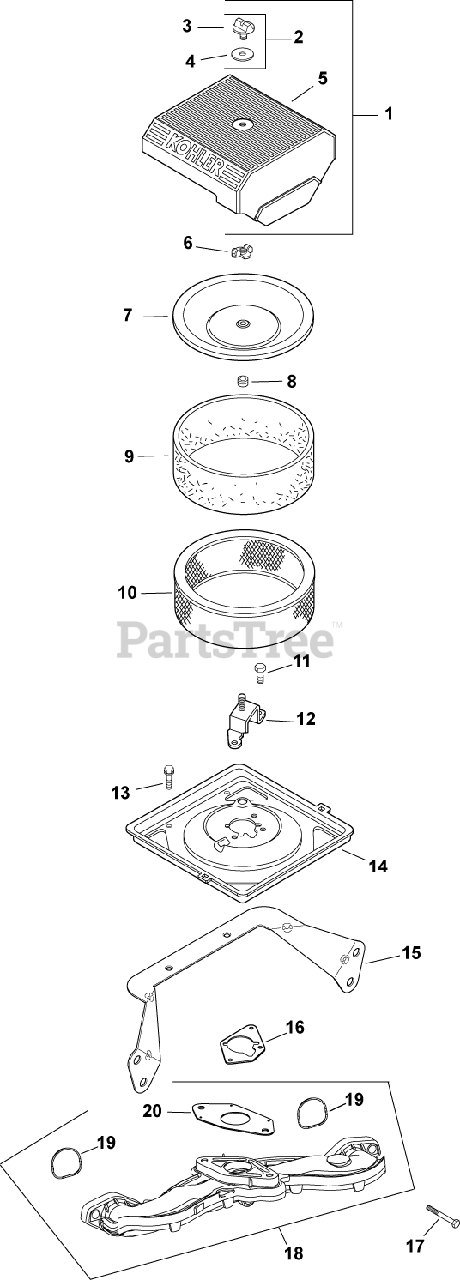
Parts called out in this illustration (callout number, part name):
1	KIT, AIR CLEANER COVER
2	KIT, KNOB W/SEAL
3	KNOB, COVER
5	COVER, AIR CLEANER
6	NUT, WING
7	COVER, INNER AIR CLEANER
8	SEAL, BREATHER
9	PRE-CLEANER (HIGH)
10	ELEMENT, AIR FILTER (HIGH) - Also available Retail Packaged 24 883 03-S1 Air Filter Kit
11	SCREW, FLG THD FRM M6X1.0X16
12	BRACKET, AIR CLEANER-USE 24 126 210-S
13	SCREW, FLG THD FRM M5X.8X10
14	BASE, AIR CLEANER -USE 24 094 88-S
15	BRACKET, AIR CLEANER BASE
16	GASKET, AIR CLEANER BASE
17	SCREW, FLG M6X1.0X40
18	MANIFOLD, INTAKE - PLASTIC-USE 24 164 93
19	O-RING, INTAKE PORT
20	GASKET, CARBURETOR
